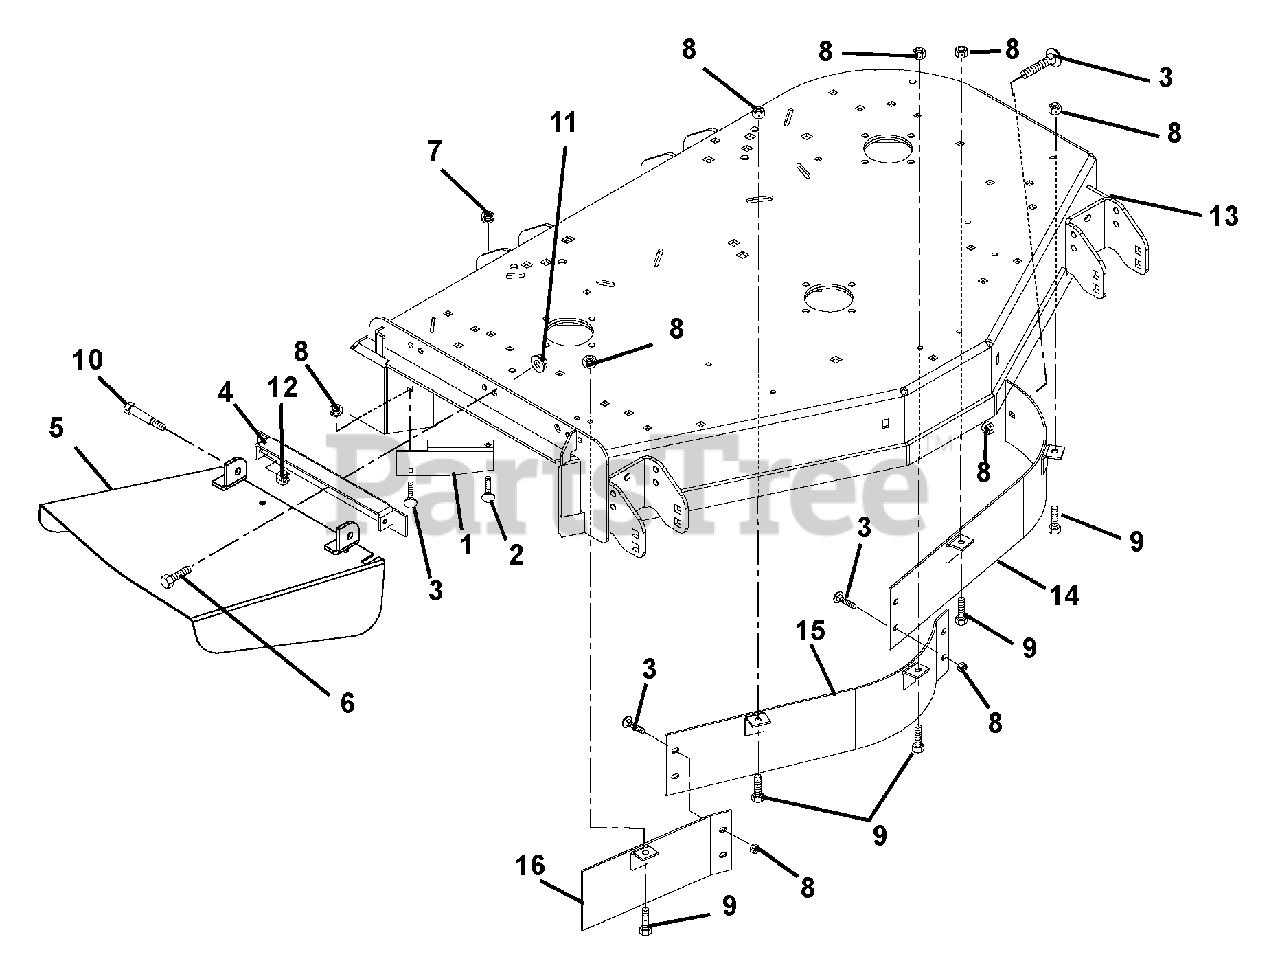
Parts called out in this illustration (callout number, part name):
1	Deflector- 60"
1	Deflector- 72"
2	Bolt-Round Head Square Neck .38-16 x .75 Grade 5
3	Bolt-Round Head Square Neck .31-18 x .75 Grade 5
4	Weldment, Discharge Chute Bracket
5	Chute-Discharge
6	Bolt-Hex .38-16 x 1.00 Grade 5
7	Nut-Locking-Top-Flange .38-16
8	Nut, Locking-Top-Flange .31-18
9	Bolt, Hex .31-18 x .75 Grade 5
10	Bolt, Shoulder .38-16 x .50 Socket Head
11	Nut, Flange .375-16
12	Nut, Locking-Center .38-16
13	Weldment, 60" Mower Deck
13	Weldment, 72" Mower Deck- Float
14	Weldment, Upper Baffle Left 60"
14	Weldment, Baffle, Left Front-72"
15	Weldment, Baffle, Center Front 60"
15	Weldment, Baffle, Center Front 72"
16	Weldment, Baffle, Right Front 60"
16	Weldment, Baffle, Right Front 72"
